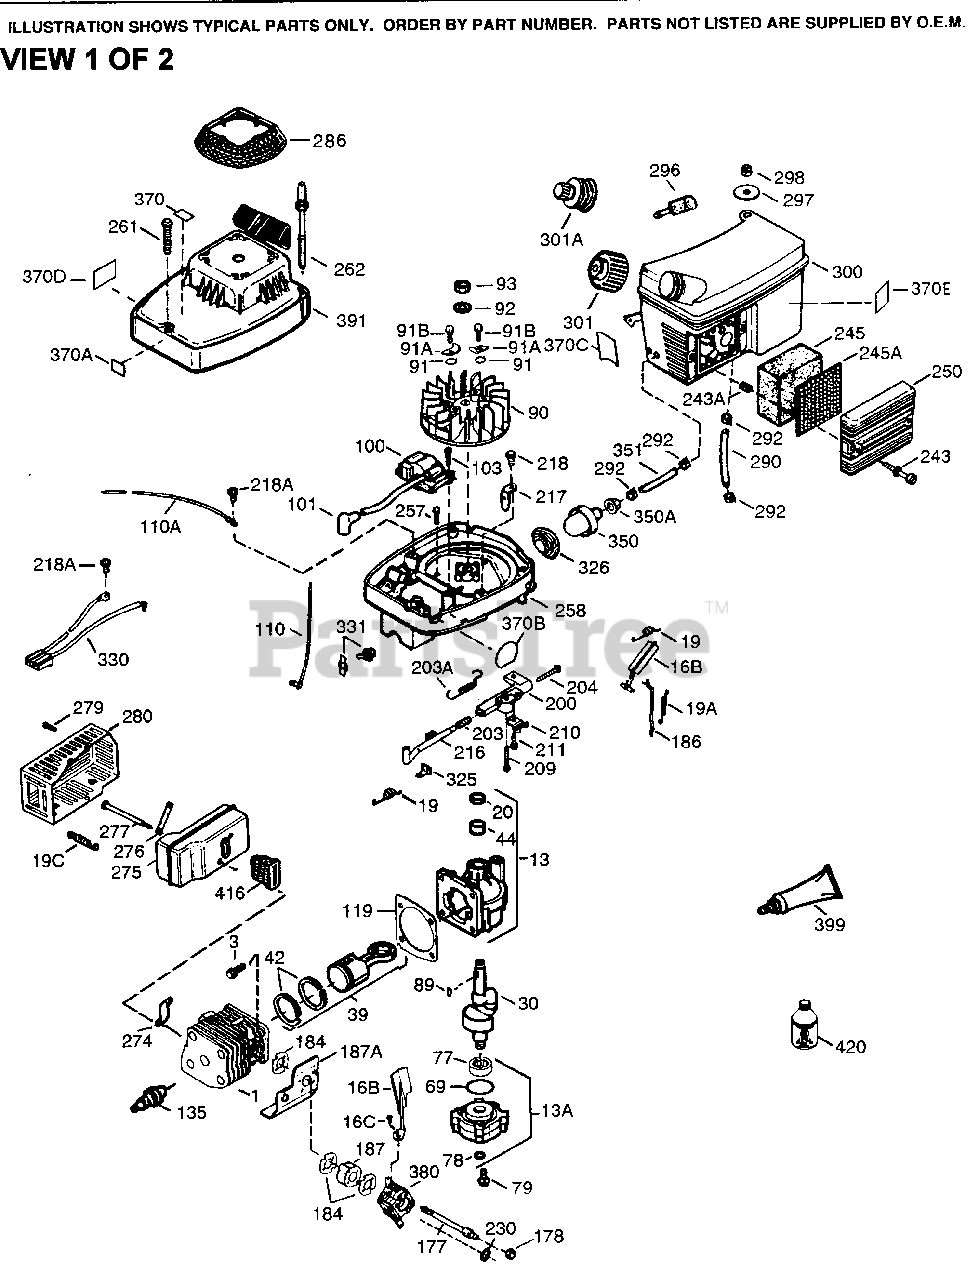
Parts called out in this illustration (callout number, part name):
1	"Cylinder (Incl. 119, 184, 187 & 187A)
3	Screw, Torx T-30, 1/4-20 x 43/64"
13	Crankcase Ass'y. (Incl. 20, 44 & 69)
13A	Crankcase Cover Ass'y. (Incl.77 & 78)
16B	Air Vane
16C	Screw, Torx T-8, 3-48 x 7/32"
19	Governor Spring
20	Oil Seal
30	Crankshaft
39	Piston & Rod Ass'y. (Incl. 42)
42	Ring Set
44	Cartridge Bearing
69	"O" Ring
77	Cartridge Bearing
78	Oil Seal
79	Screw, 1/4-20 x 3/4"
89	Flywheel Key
90	Flywheel
91	Pawl Spring
91A	Starter Pawl
91B	Screw, 12-24 X 11/64"
92	Belleville Washer
93	Flywheel Nut
100	Solid State Ignition (Incl. 101)
101	Spark Plug Cover
103	Screw, Torx T-15, 10-24 x 1"
110	Ground Wire
119	Cylinder Head Gasket
135	Resistor Spark Plug (RCJ6Y)
177	Carburetor Mounting Stud
178	Lock Nut, 10-24
184	Carburetor Gasket
187A	Air Baffle (Incl. 184 & 187)
200	Speed Control Body
203	Compression Spring
204	Screw, 8-32 x 1"
209	Screw, 8-32 x 1"
210	Conduit Clip
211	Screw, 10-32 x 1/2"
216	R.P.M. Adjusting Lever
230	"O" Ring
243	Screw, 10-32 x 29/32"
243A	Thread Insert
245	Air Filter (Poly) (also available in Packaged Part #740097 (incl. 450255 & 450257))
250	Air Cleaner Cover
257	Screw, 10-24 x 1/2"
258	Blower Housing Base
261	Screw, 8-32 x 1-9/16"
274	Exhaust Gasket
275	Muffler (Incl. 274 & 277)
277	Screw, 1/4-20 x 2.409"
290	Fuel Line
292	Fuel Line Clamp
298	Lock Nut, 8-32
300	Fuel Tank Incl. 290, 292, 298, 301 &3 70C
301	Fuel Cap
326	Blower Housing Plug
331	Toggle Switch
370A	Instruction Decal
370B	Plug Decal
370C	Choke Decal
380	Carburetor (Incl. 184)
391	Rewind Starter & Housing Ass'y.
420	2-Cycle Oil with Fuel Stabilizer - 8 oz.
